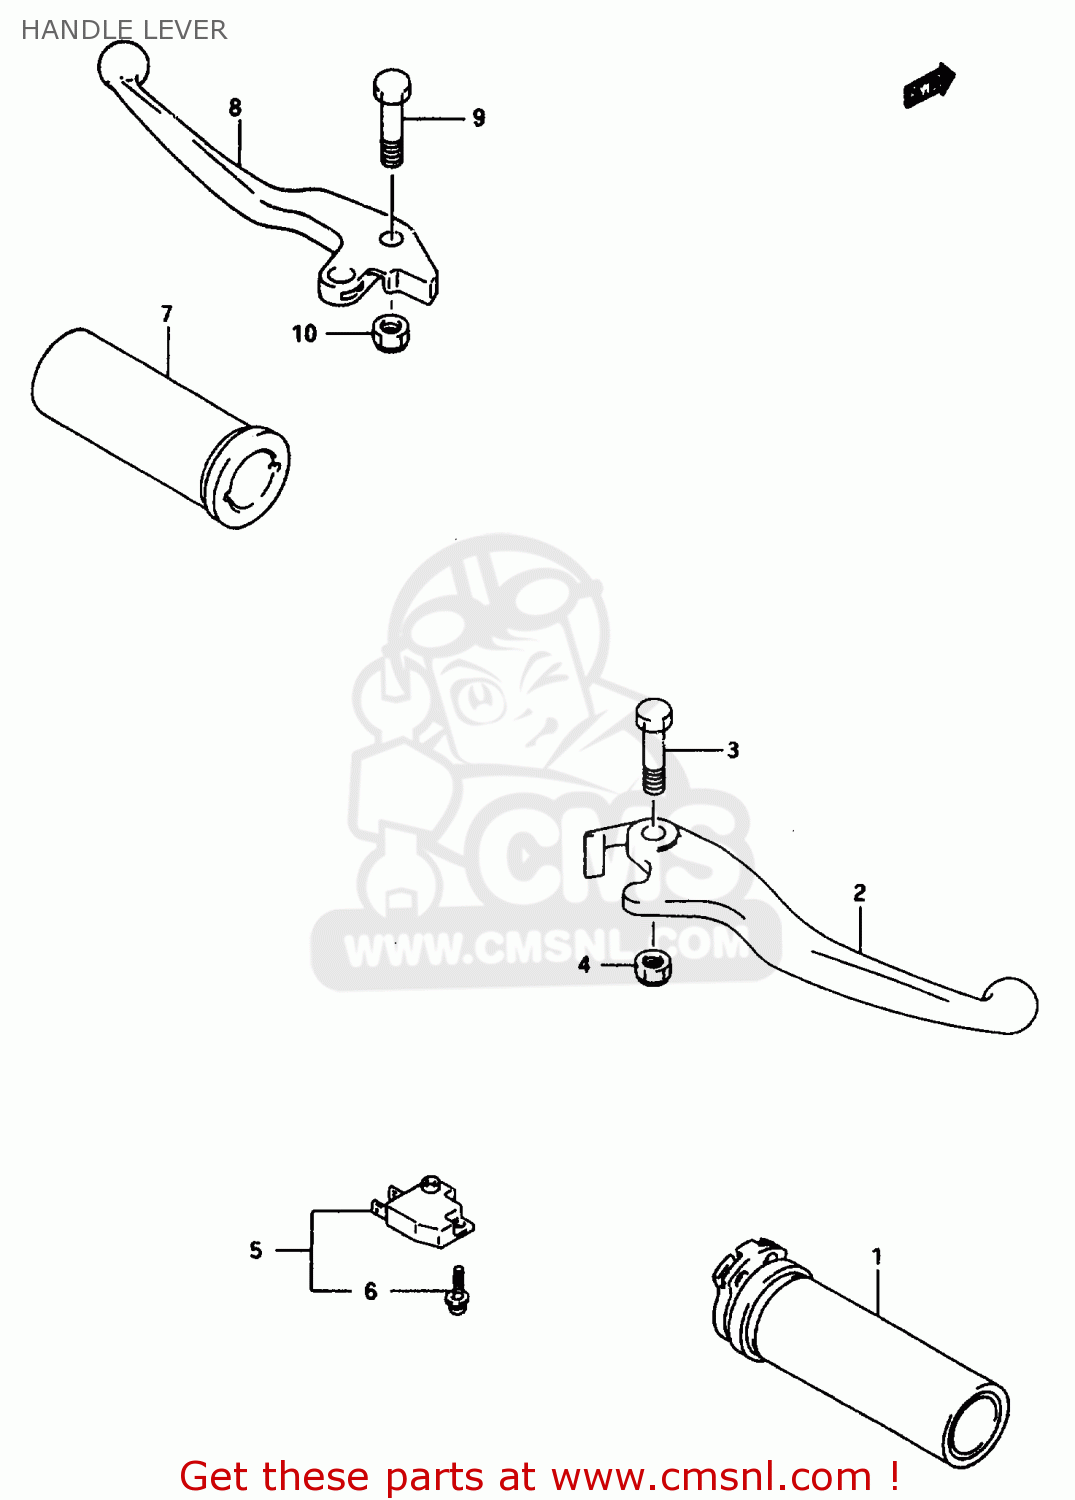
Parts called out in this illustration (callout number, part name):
1	GRIP,THROTTLE
2	LEVER,BRAKE
3	BOLT,LEVER SET
4	NUT 6MM
5	SWITCH ASSEMBLY,STOP
6	SCREW
7	GRIP,L
8	LEVER,CLUTCH (SILVER)
9	BOLT,LEVER SET
10	NUT 6MM
